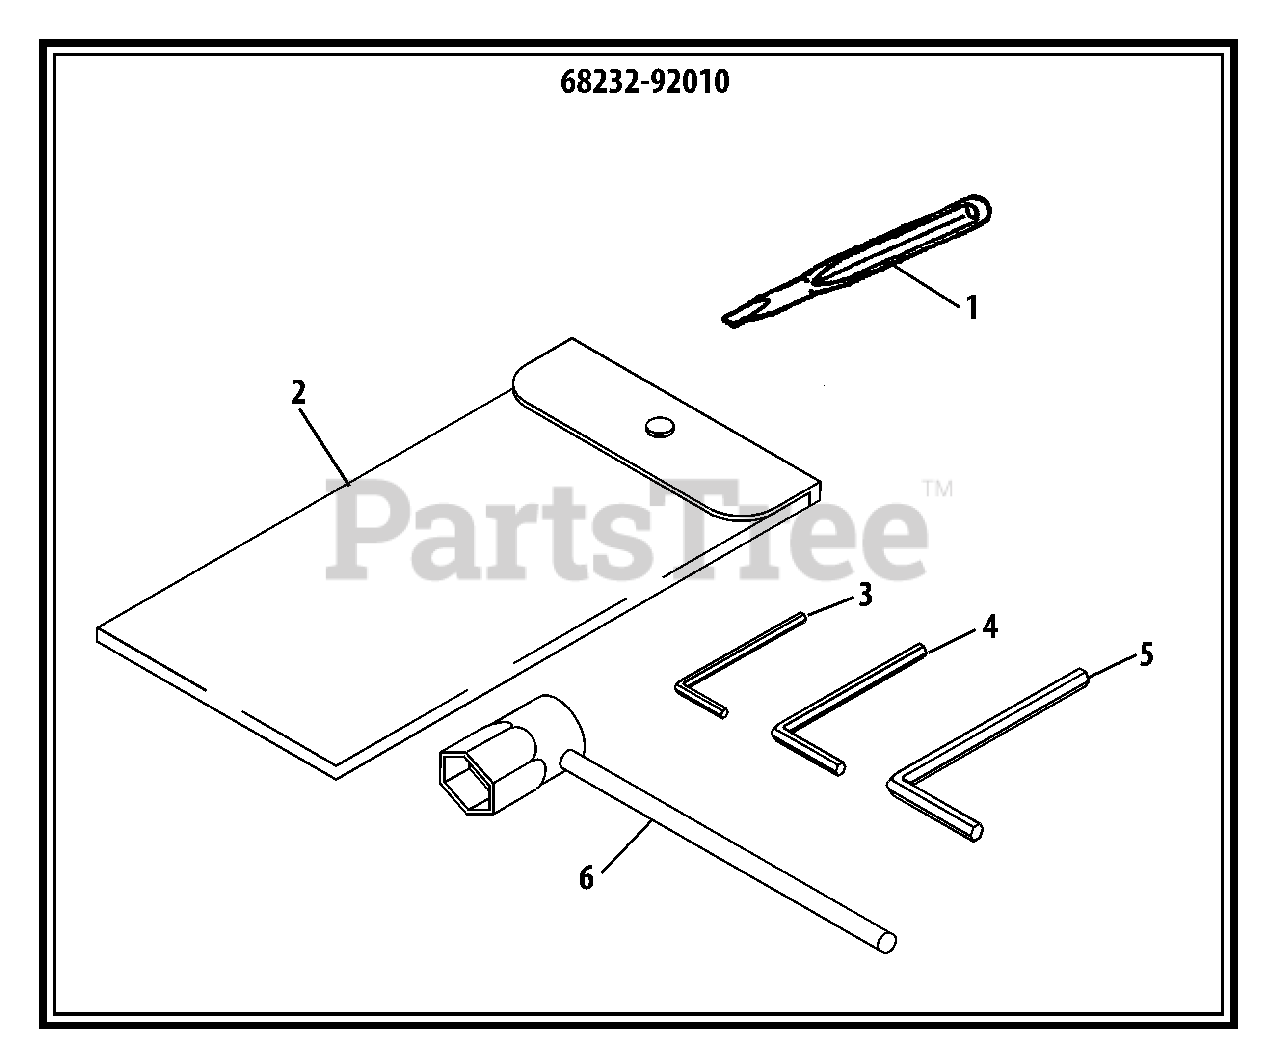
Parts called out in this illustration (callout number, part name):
1	SCREWDRIVER, PLASTIC
2	BAG, TOOL
3	WRENCH, ALLEN 3 MM
4	WRENCH, ALLEN 4 MM
5	WRENCH, ALLEN 5 MM
6	T-WRENCH 19 MM
68232-92010	TOOL KIT, SERVICE
